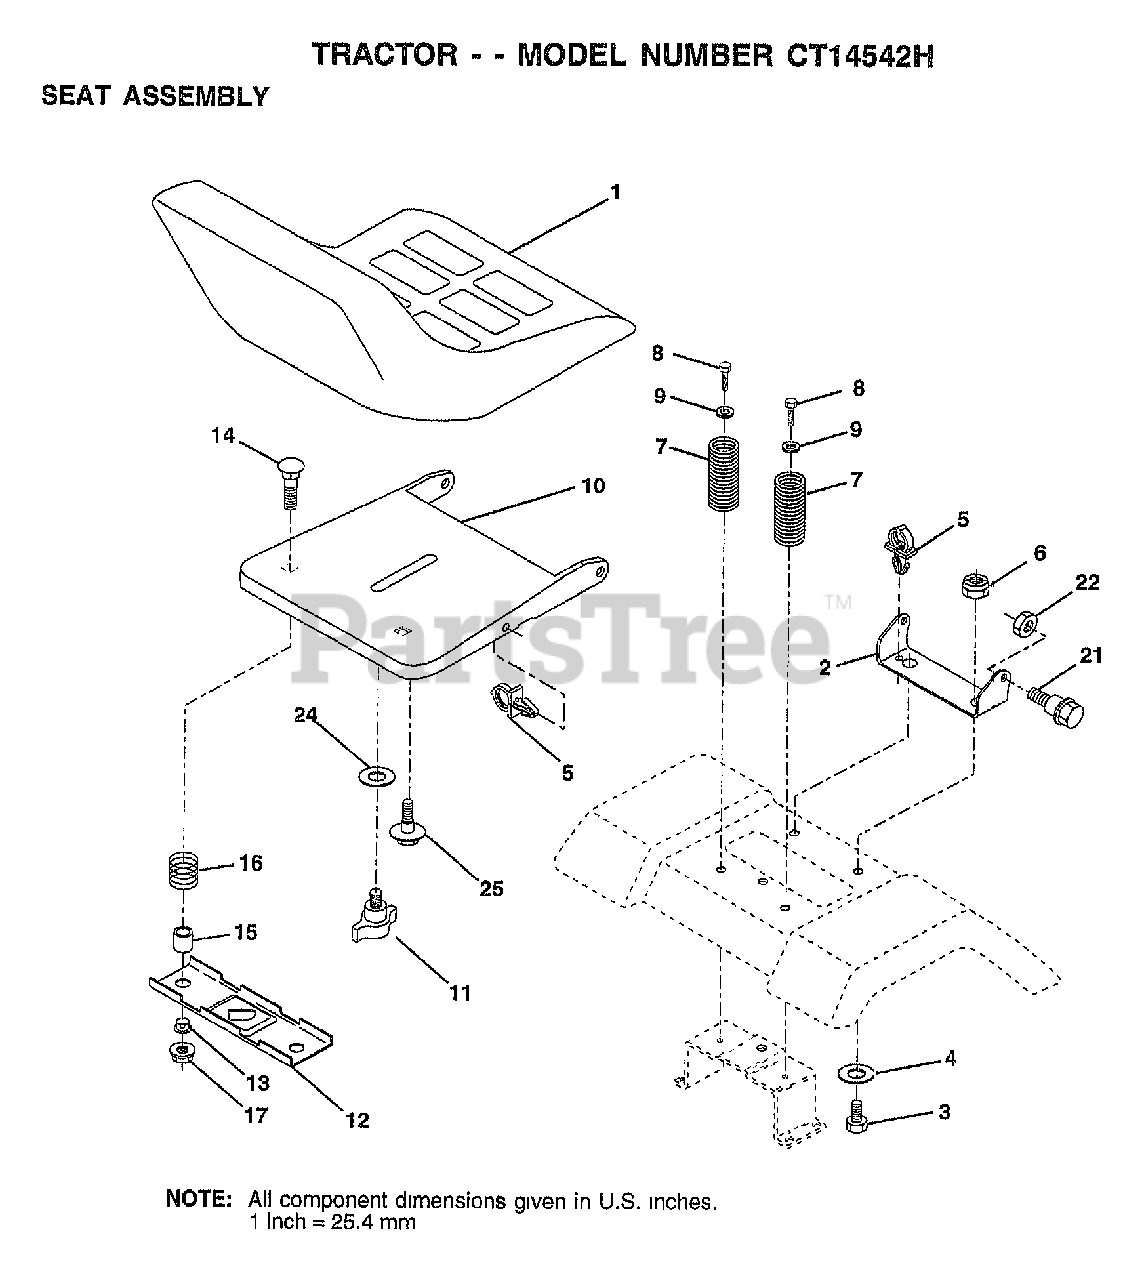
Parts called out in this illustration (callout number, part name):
2	BRACKET PVT SEAT
3	BOLT
4	WASHER PM
5	CLIP.PUSH-IN.HING
6	NUT
7	SPRING COMPRESSIO
8	SCREW GTV
9	WASHER
10	PAN-SEAT
11	KNOB.SEAT.ADJ.WINGNUT
12	BRKT SWITCH
13	BUSHING
14	BOLT-RD HD SQ NK
15	SPACER SPLIT
16	SPRING COMPRESSED
21	"BOLT,SHOULDER"
22	NUT
24	WASHER
25	"BOLT,SHOULDER"
